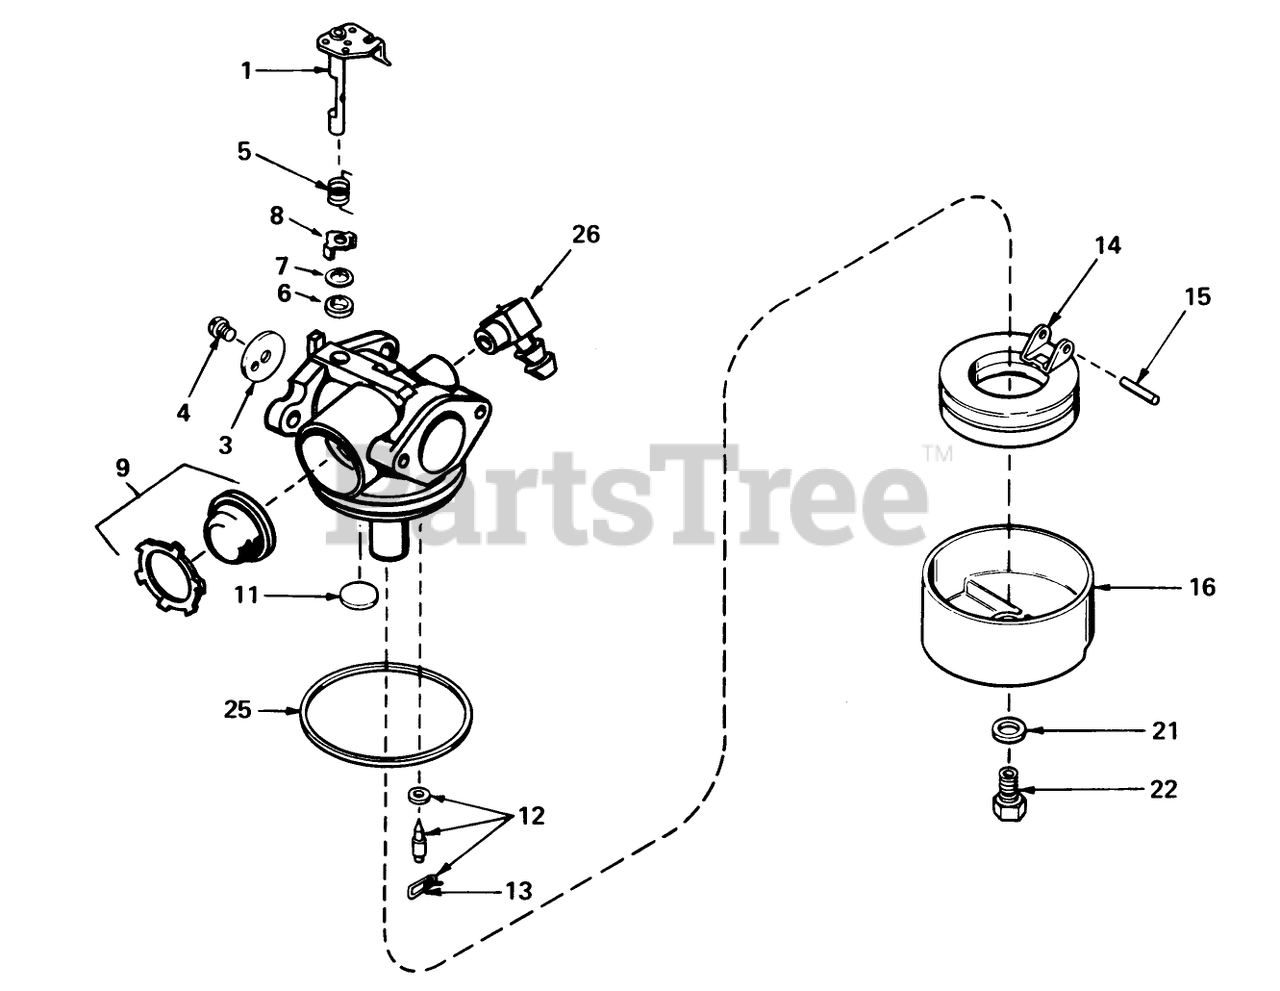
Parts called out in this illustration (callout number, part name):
1	Throttle Shaft and Lever ASM
3	Throttle-Shutter
4	Screw-Shutter
5	Spring, Return
6	Seal-Dust
7	Washer-Seal, Dust
8	Retainer, Seal
9	Primer Assy.
11	Plug-Welch, Atmospheric Vent
12	Inlet Needle, Seat Clip Assy. (Incl. No. 13)
13	Clip-Spring
14	Float
15	Shaft-Float
16	Bowl Float
21	Gasket-Bowl
22	Nut-Float Bowl
25	O Ring-Bowl, Float
26	Fitting-Fuel
